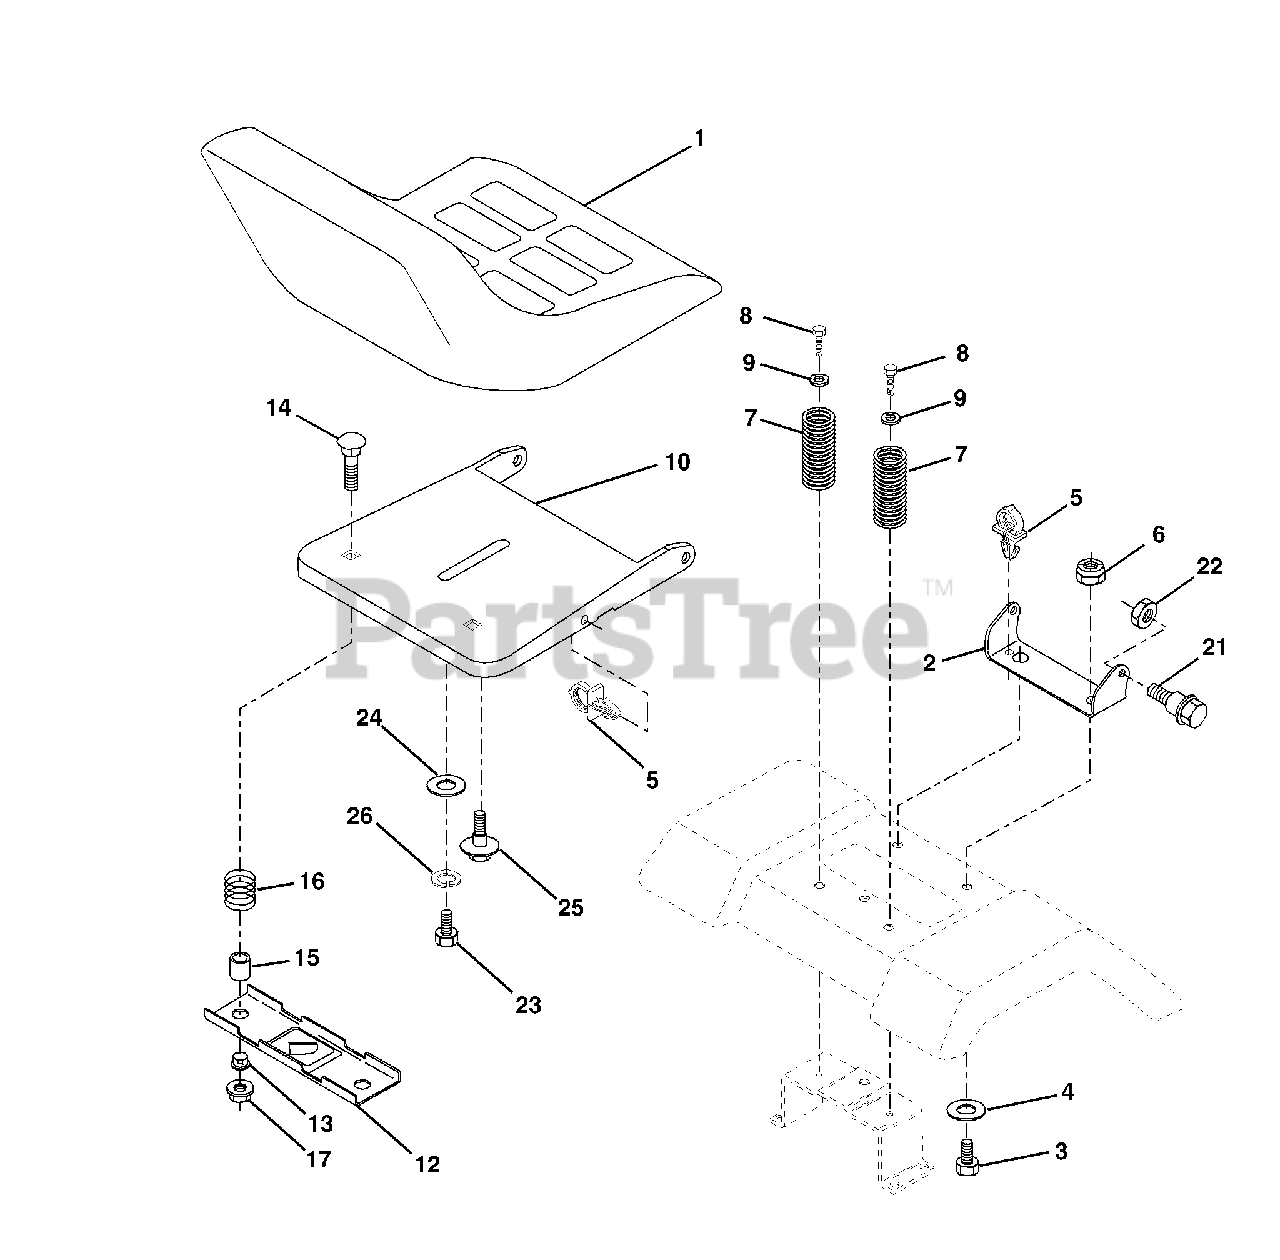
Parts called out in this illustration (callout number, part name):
2	Bracket Seat Pivot
3	Bolt Hex 3/8 - 16 x 1
4	Washer 13/32 x 1 x10Ga.
5	Clip Push-In Hinged
6	Nut Lock Hex w/Ins 3/8 - 16
7	Spring Seat Cprsn 2 250 Blk Zi
8	Screw 3/8-16 x 1.5
9	Washer 13/32 x 1 x 14 Ga
10	Pan Pnt Seat (Blk)
12	Bracket Pnt Mounting Switch
13	Bushing Snap Blk Nyl
14	Bolt Rdhd Sht Nk 1/4 - 20 x 1 -1/2
15	Spacer Split .28 x .96
16	Spring Cprsn
17	Nut Lock 1/4 Lge Flg
21	Bolt Shoulder 5/16-18 Unc-2A
22	Nut Lock Hex w/Ins 5/16 - 18
23	Bolt Hex
24	Washer 17/32 x 1-3/16 x 12 Ga
25	Bolt Shoulder 5/16-18 x .62
26	Washer Lock Hvy Hlcl Spr 1/2
